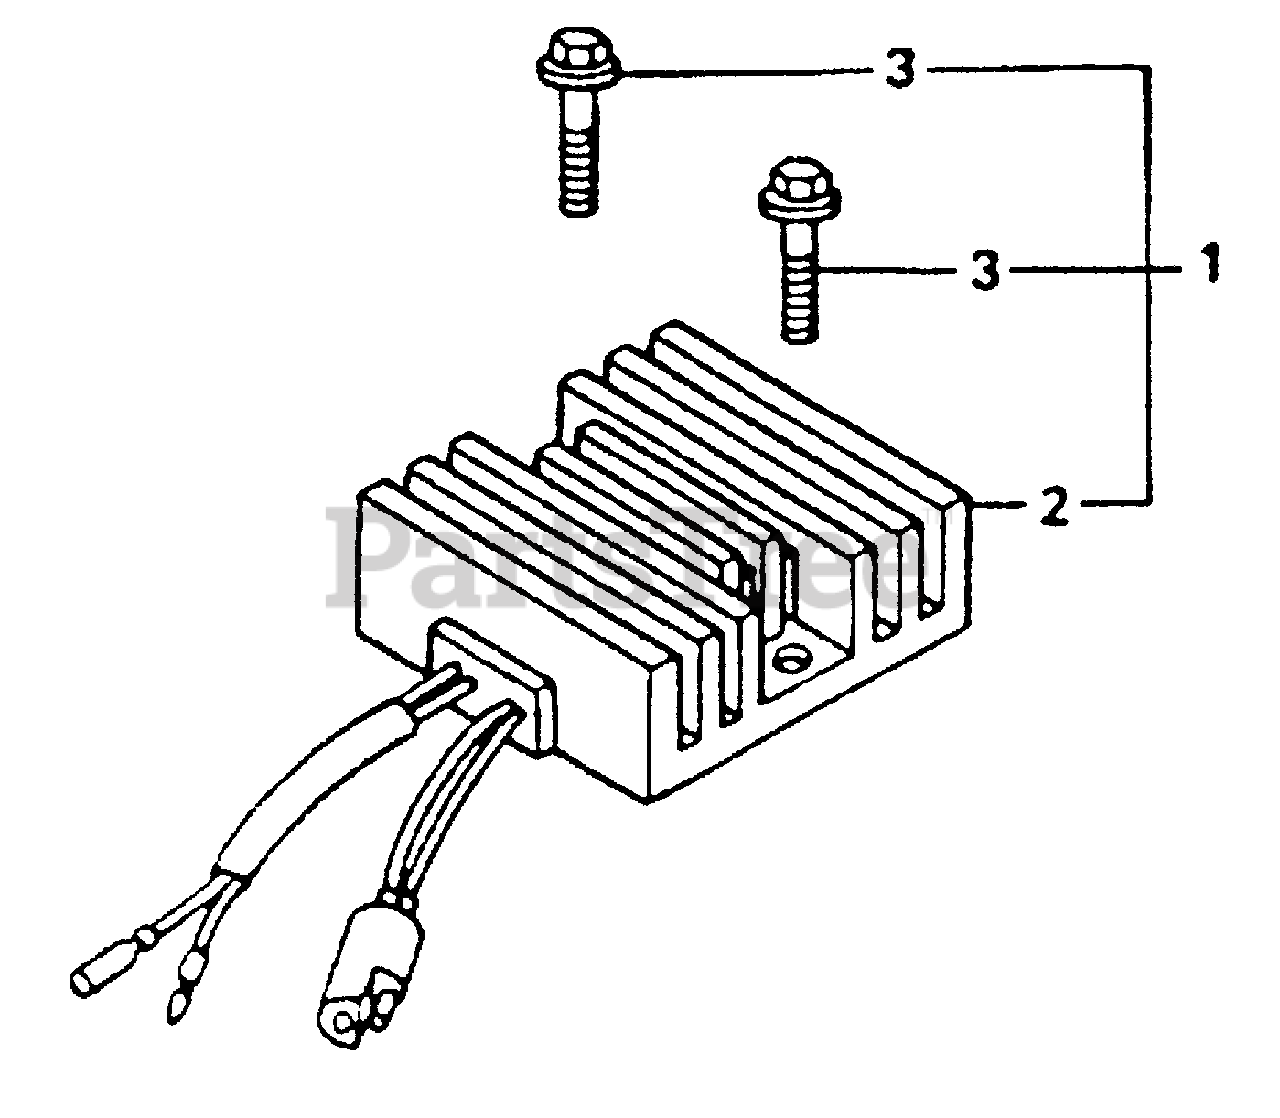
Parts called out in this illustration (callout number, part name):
1	RECTIFIER KIT (10A)
2	RECTIFIER ASSY. (10A)
3	BOLT, FLANGE (6X12)
